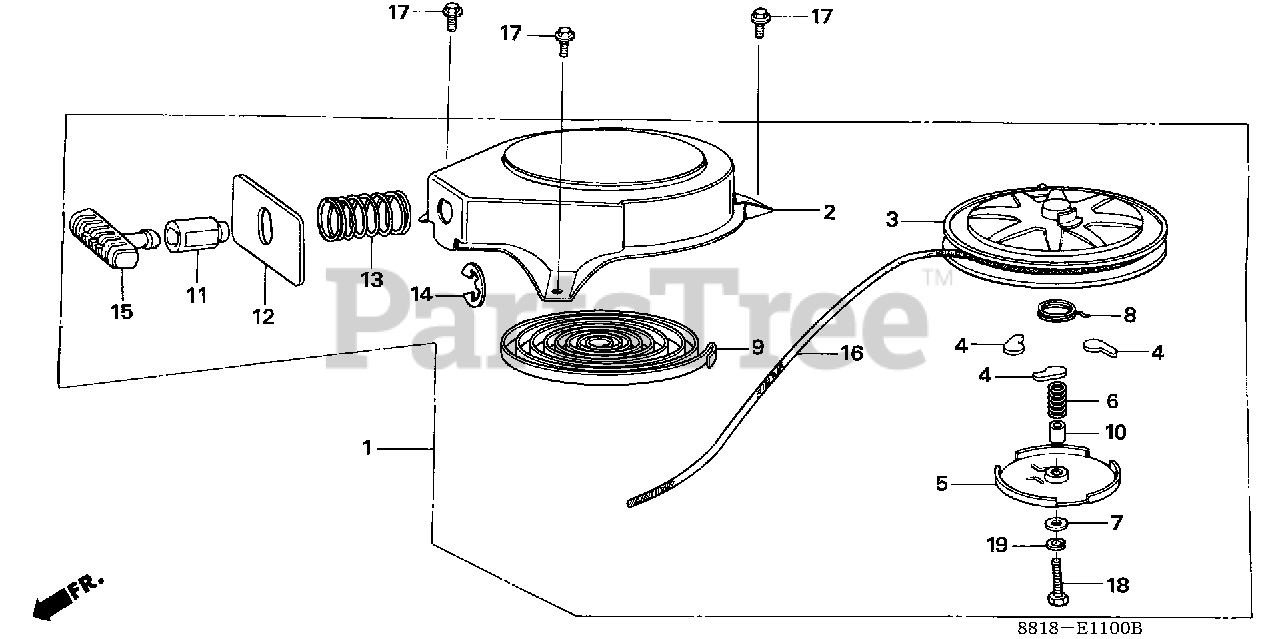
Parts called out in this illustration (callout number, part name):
1	STARTER ASSY., RECOIL
2	CASE, RECOIL STARTER
3	PULLEY, RECOIL STARTER
4	RATCHET, STARTER
5	PLATE, FRICTION
6	SPRING, FRICTION
8	SPRING, SETTING
9	SPRING, RECOIL STARTER
11	GUIDE, ROPE
12	PLATE, SEAL
13	SPRING, SEAL PLATE
15	GRIP, STARTER
16	ROPE, RECOIL STARTER (NA USE ALT:08540-ZG921-11)
17	BOLT, FLANGE (6X12)
18	BOLT, HEX. (6X25)
19	WASHER, SPRING (6MM)
